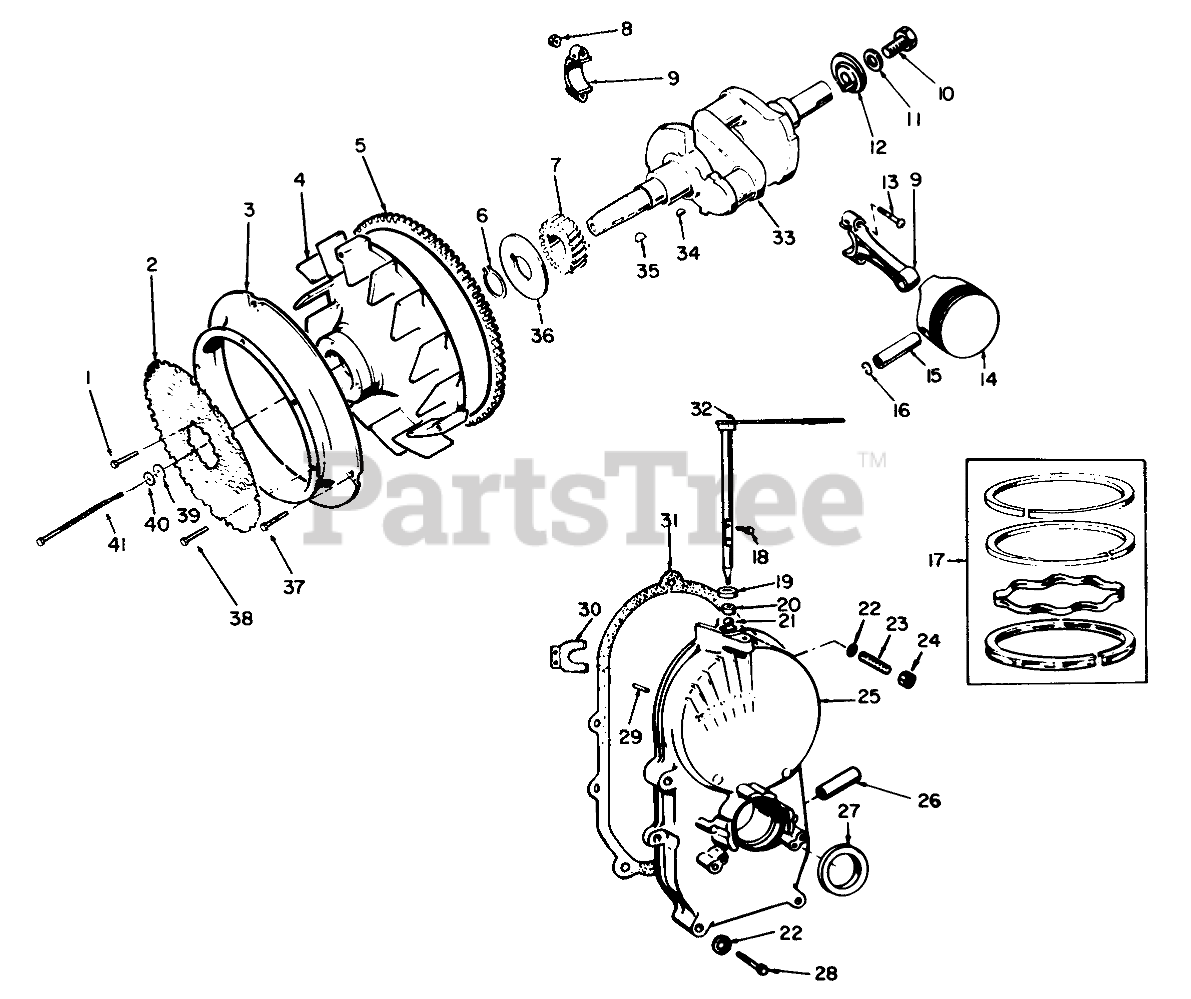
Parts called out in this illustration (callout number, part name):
1	HX HD LOCK CAPSCREW
2	SCREW W/INLET
3	BLOWER VENTURI
4	Flywheel (Incl. Ref. #5)
9	Rod, Connecting-Standard (Incl. Ref. #8 & 13)
10	HX HD CAPSCREW
11	WASHER-LOCK
12	Weight, Balance
14	Piston & Pin-Standard (Incl. Ref. #15 & 16)
16	Piston Pin
17	RING SET
18	SCREW-PAN HD
20	BEARING
22	WASHER
23	STUD-GEAR COVER
24	NUT-GEAR COVER
25	Gear Case Assembly (Incl. Ref. #18-21, 23-24, 27-28 & 30)
26	TUBE-PORT, VACUUM
28	SCREW-HH
29	PIN-DOWEL
31	Ring Gear
32	SHAFT/ARM-GOVERNOR
33	CRANKSHAFT
35	KEY KIT
36	WASHER
37	SCREW-HWH
38	Screw, Tapping Hex Washer Hd.
39	WASHER-FLAT
40	WASHER-LOCK
41	SCREW
